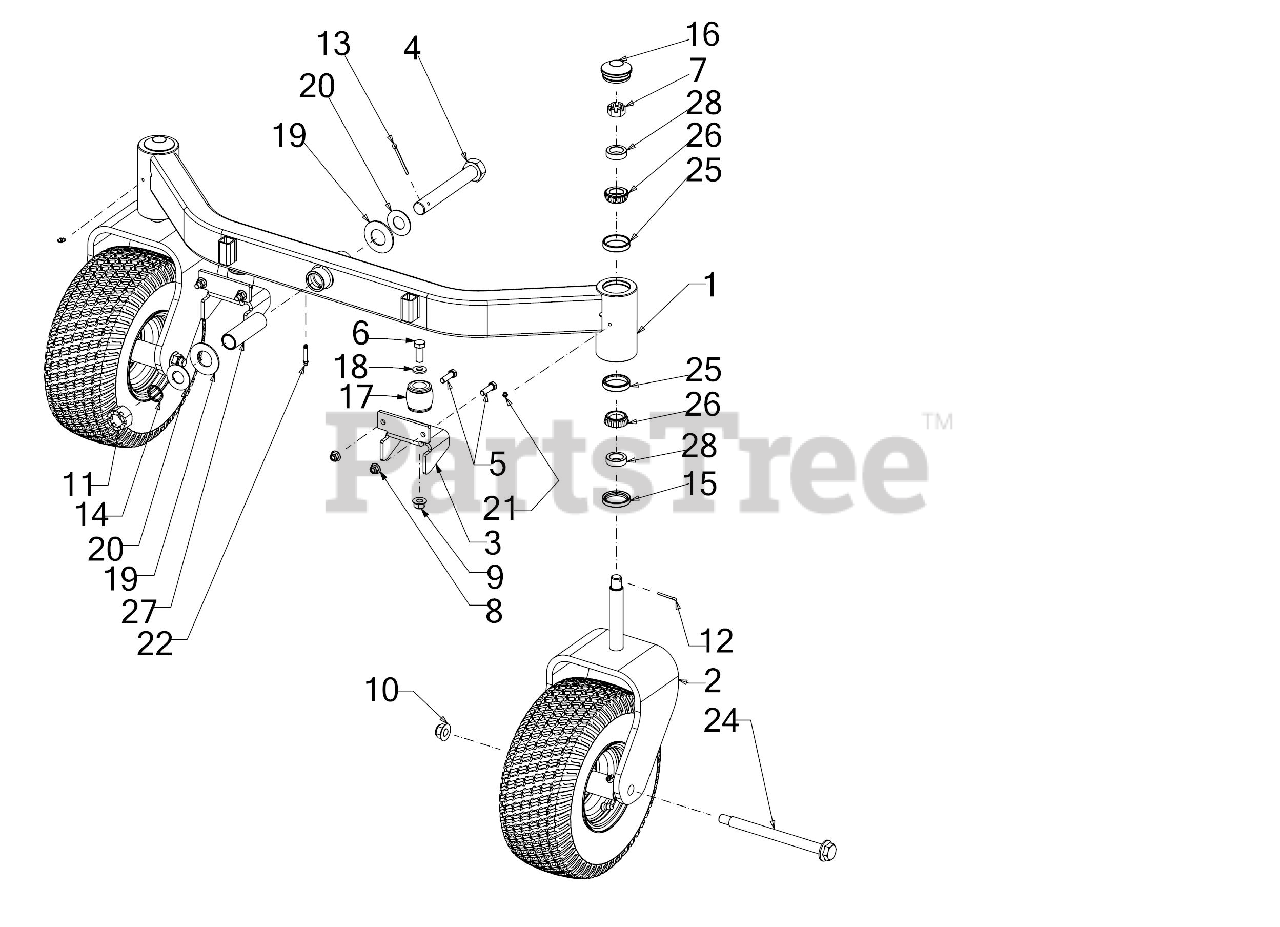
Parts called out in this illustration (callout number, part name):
1	FRONT AXLE ASSEMBLY
2	FRONT CASTER ASSEMBLY (LAPBAR)
3	AXLE BUMPER MOUNTING BRACKET
4	HEX HEAD SCREW 1-14 X 7 GR5
5	SCREW 3/8-16 x 1.25 GR5
6	SCREW 1/2-13 x 1.25 GR5
7	HEX NUT CASTLE 3/4-16
10	FLANGE LOCK NUT
11	CASTLE NUT 1.0-14 GR5
12	COTTER PIN-5/32 DIA
13	COTTER PIN
14	RETAINING RING
16	AXLE GREASE CAP
17	AXIAL BUMPER
18	FLAT WASHER .510 x 1.000 x .125
19	BELL WASHER 1.25ID x 2.5 x .180
20	FLAT WASHER 1.0 x 2.0 x .075
21	GREASE ZERT 1/4-28
22	GREASE FITTING
24	SHOULDER BOLT .750 X 8.175:5/8-11
25	BEARING CUP
26	BEARING CONE
